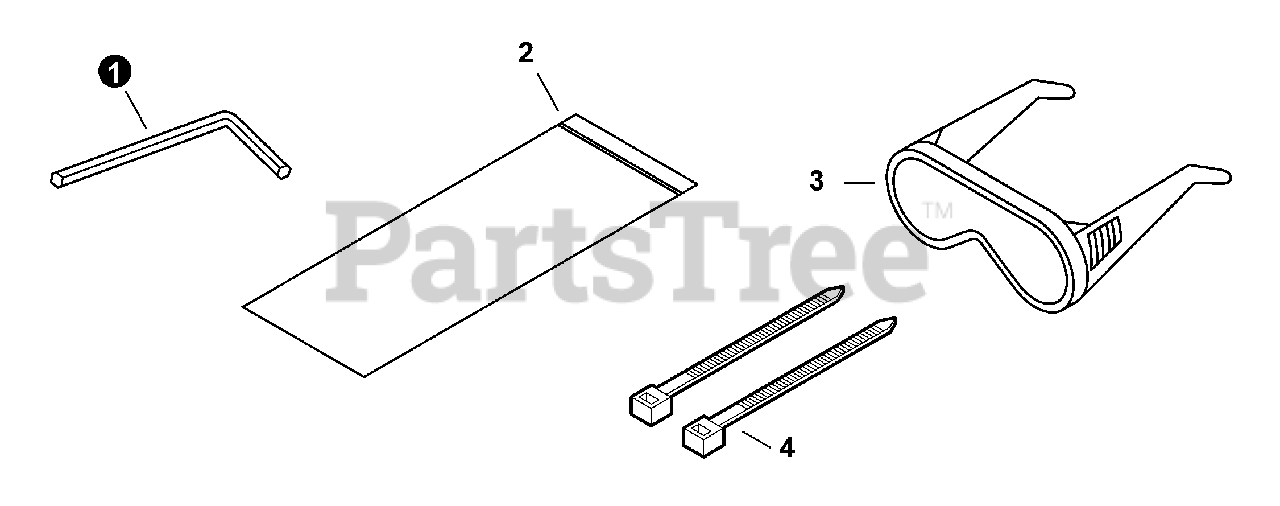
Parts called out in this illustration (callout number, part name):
1	WRENCH, ALLEN 4 MM
2	BAG, TOOL
3	GLASSES, SAFETY
4	TIE, CABLE
